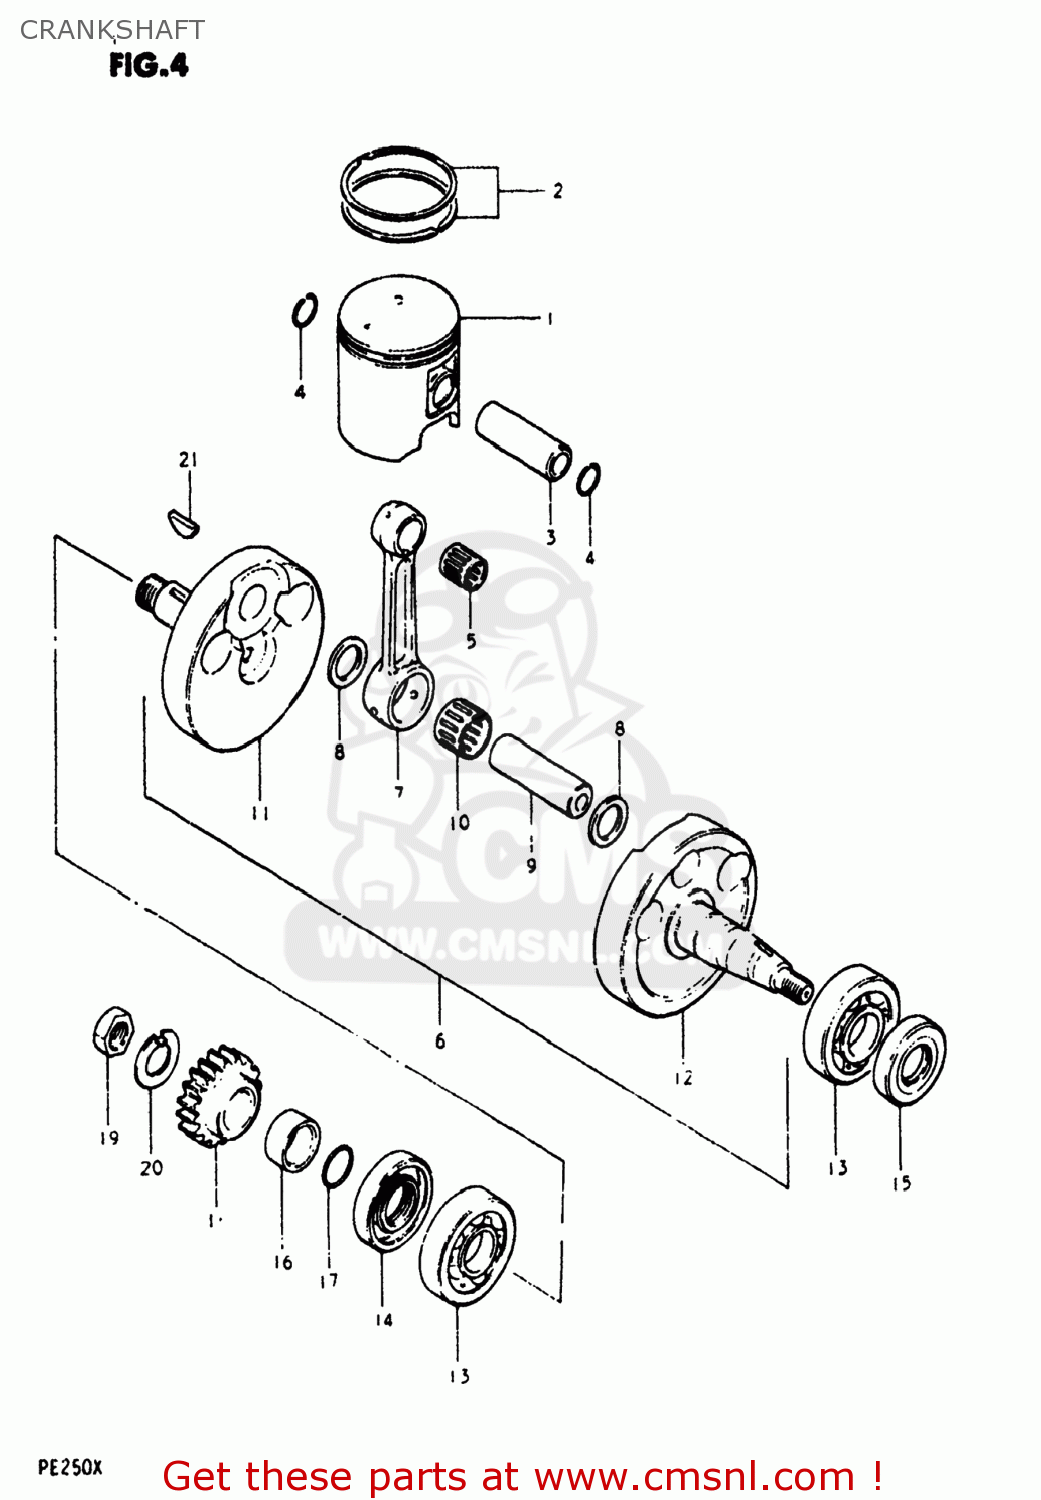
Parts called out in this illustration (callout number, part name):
1	PISTON
2	RING SET,PISTON
3	PIN,PISTON (18MM)
4	CIRCLIP
5	BEARING(18X23X22)
6	CRANKSHAFT ASSEMBLY
7	ROD,CONNECTING
8	WASHER(24X29X1.5)
9	PIN,CRANK
10	ROLLER BEARING (24X30X1
11	CRANKSHAFT
12	CRANKSHAFT,LEFT
13	BEARING
14	SEAL,OIL(32X52X8.4)
15	SEAL,OIL(24X50X9)
16	SPACER
17	O RING(D:2.4,ID:19.8)
18	GEAR,PRIMARY DRIVE
19	NUT
20	WASHER
21	KEY
